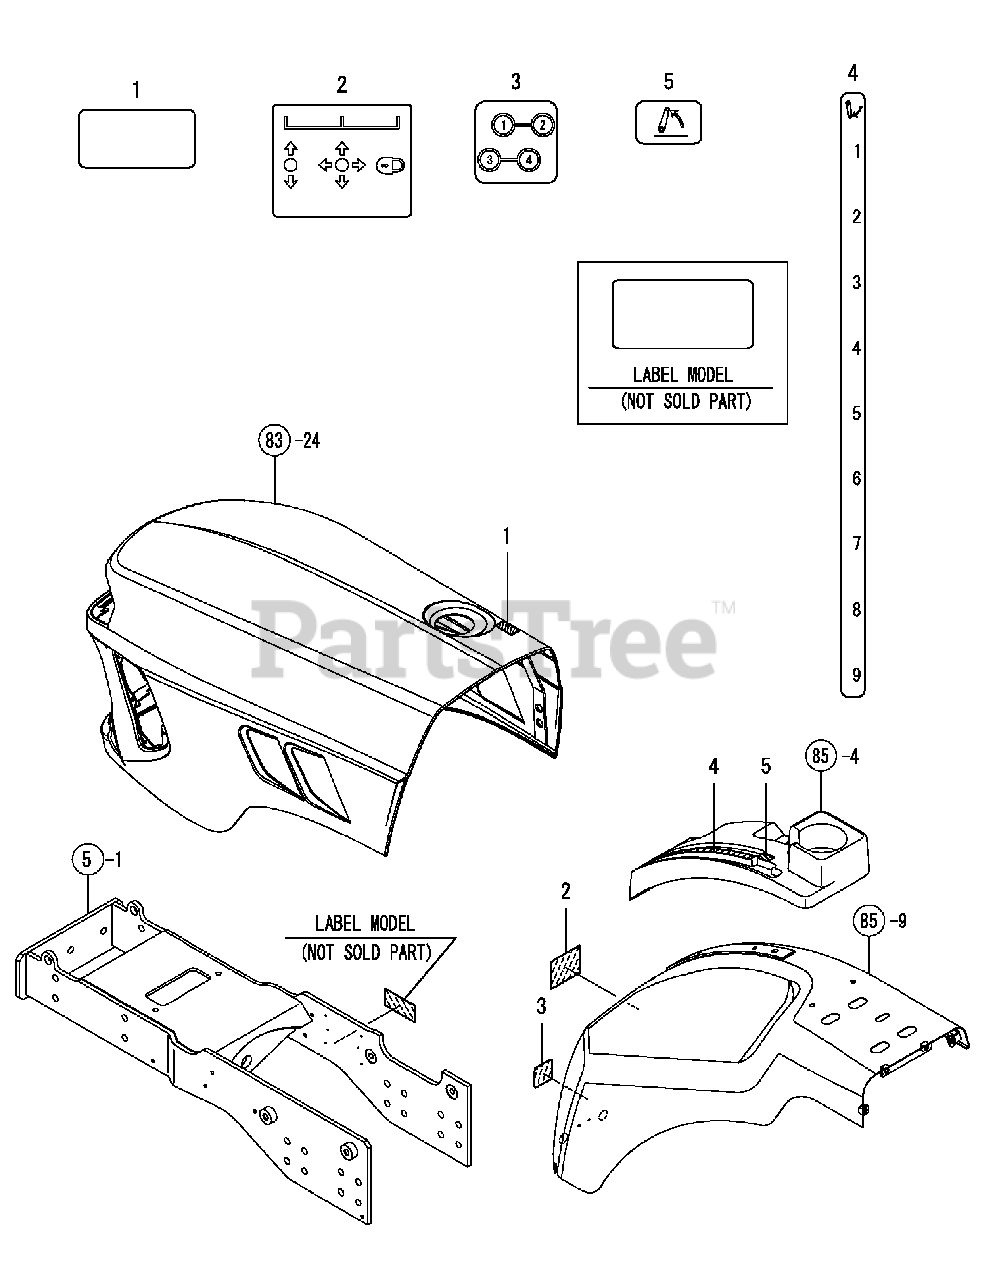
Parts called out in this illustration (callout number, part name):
1	Label, Fuel Oil
2	Label, Scv Lever
3	Label, Scv Coupler
4	Label, Hyd.Lever
5	Label B, Hyd.Lever
